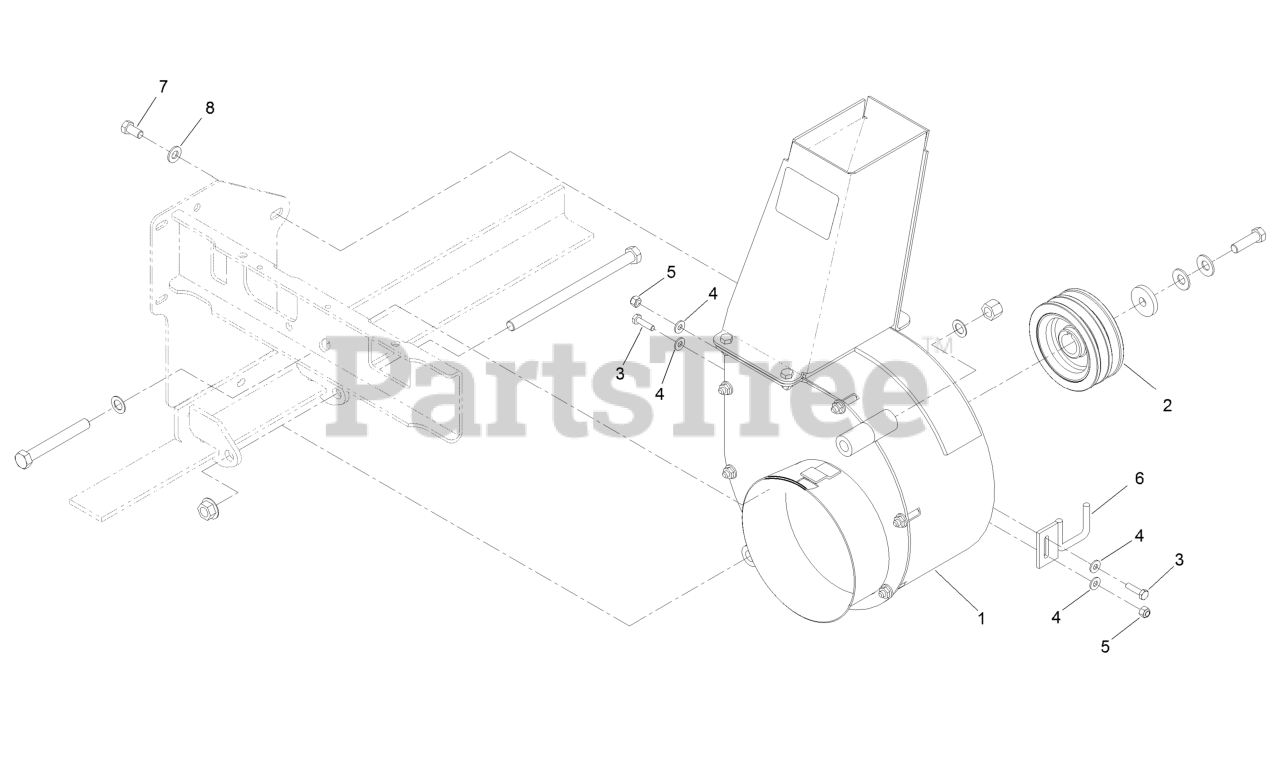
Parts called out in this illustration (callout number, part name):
1	Blower ASM
2	Sheave-Blower
3	Screw-HH
4	Washer-Flat
5	Nut-Lock, NI
7	Screw-HH
8	Washer-Flat
